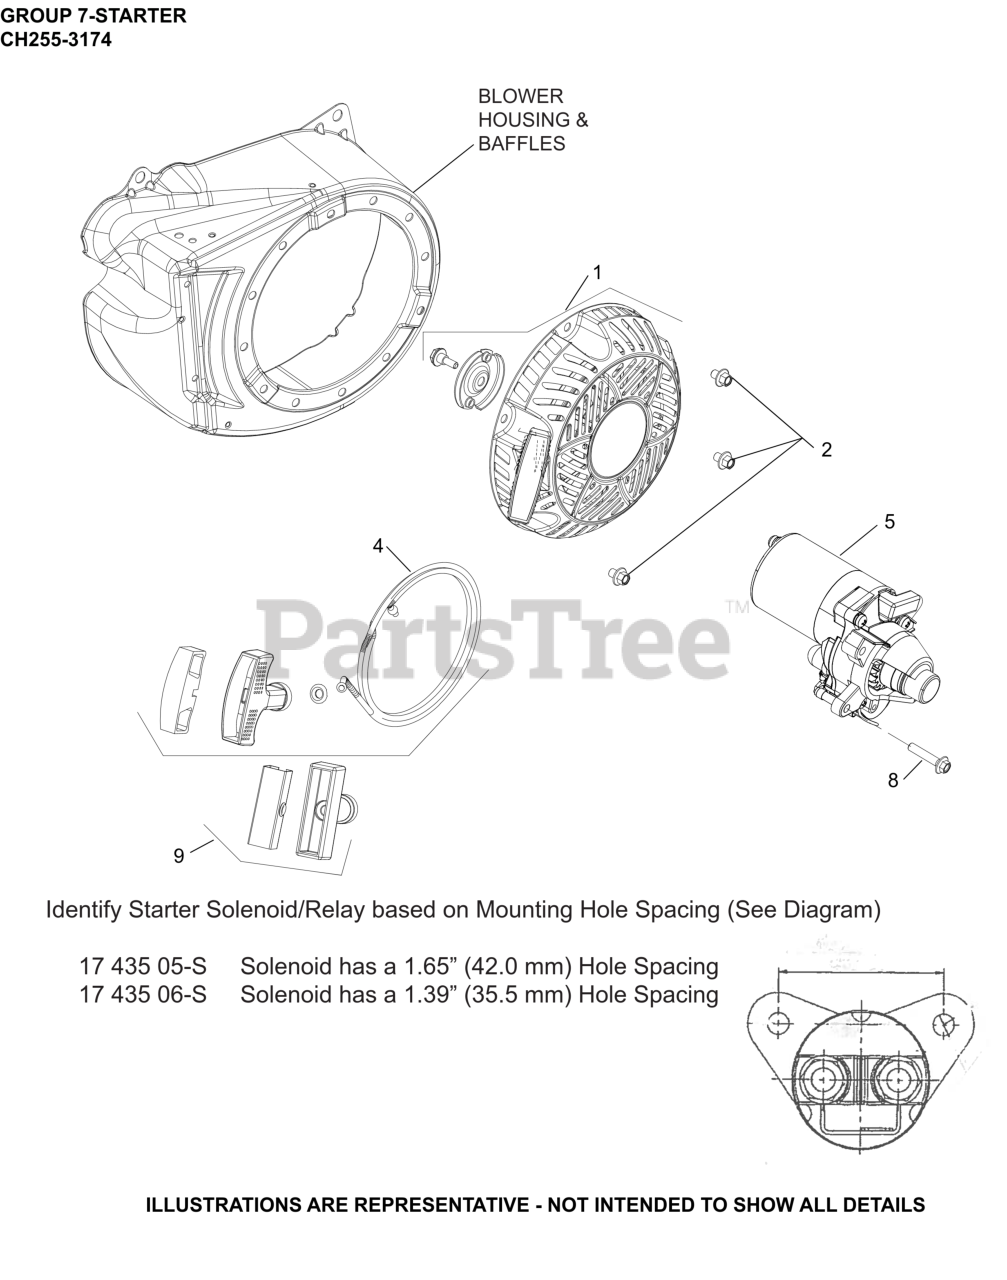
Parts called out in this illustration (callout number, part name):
1	RETRACTABLE STARTER ASSEMBLY
2	SCREW, M6 X 8 HEX FLANGE HEAD
4	ROPE, STARTING
5	ELECTRIC STARTER-BENDIX DRIVE
8	SCREW, STARTER MOUNTING
9	KIT, HANDLE
